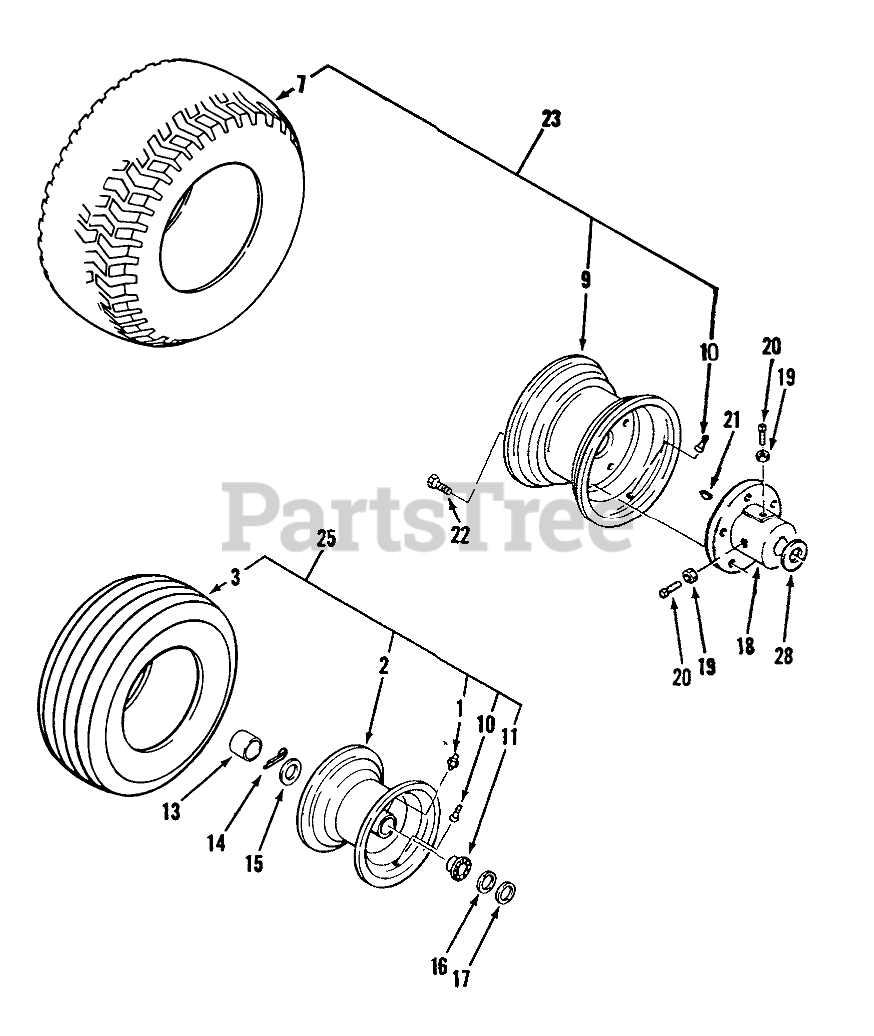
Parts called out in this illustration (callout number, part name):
1	ZERK-GREASE
2	Front Wheel (includes items 1, 10 & 11)
3	Tire (16 x 6.5-8) 2-Ply -2 Wheel Axel
7	TIRE
9	WHEEL
10	VALVE
11	BEARING-WHEEL
13	HUBCAP
14	COTTER PIN-4
15	WASHER WHEEL
16	WASHER
17	WASHER-SHIM
18	Hub Rear
19	Nut
20	Screw-Set
21	KEY-WOODRUFF
22	Lug Nut
23	ASM-Wheel& Tire
28	WASHER-THRUST
